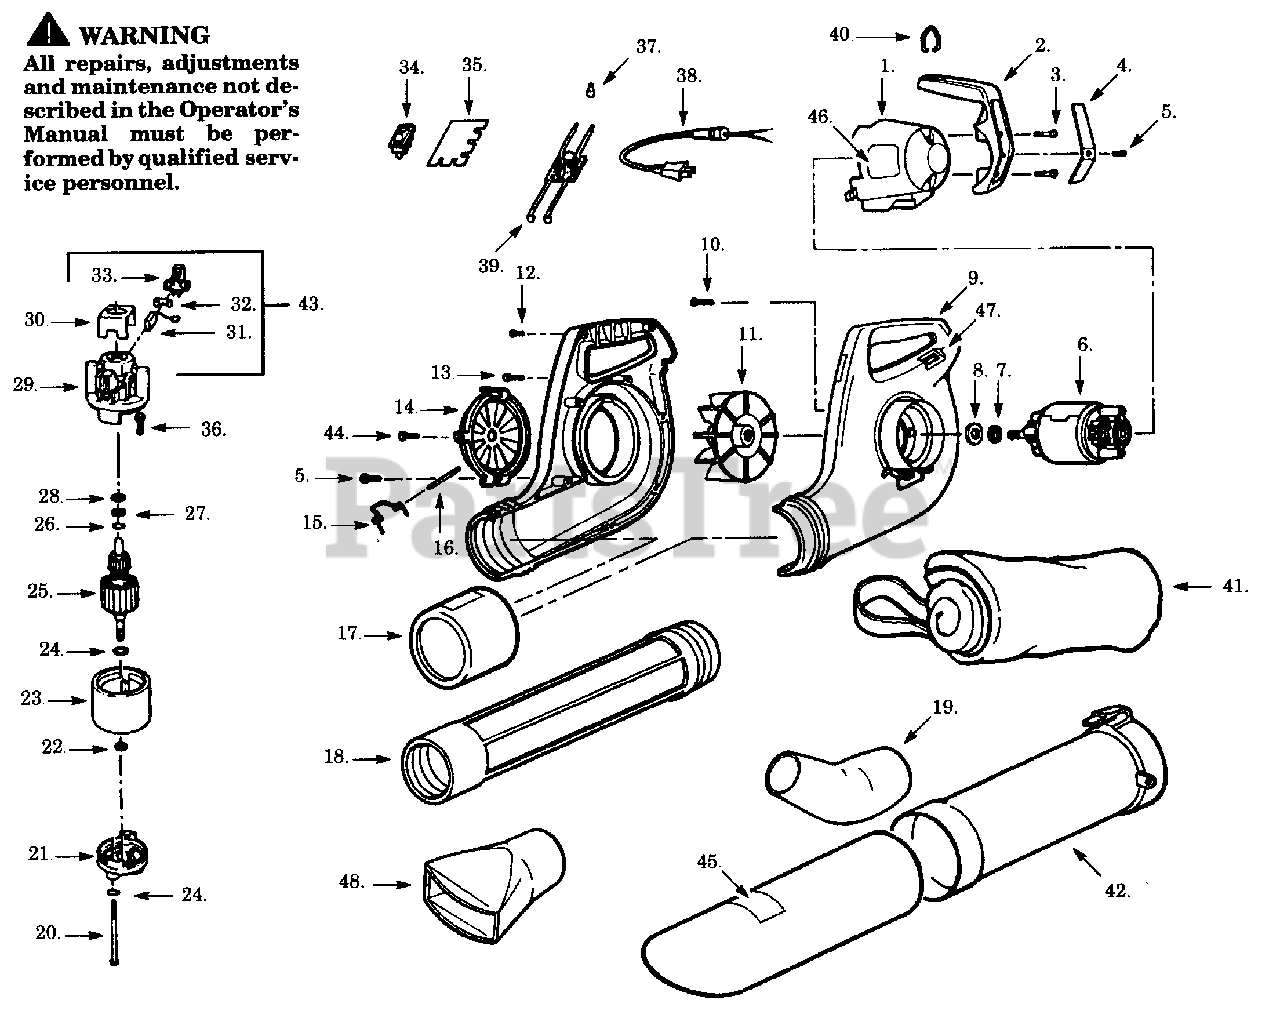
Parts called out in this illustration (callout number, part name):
1	Motor Cover
4	Plate Warning
7	Retaining Ring
9	L.H/R.H. Housing
11	Impeller Ass'y.
14	Inlet Cover
16	Hinge Pin
17	Ferrule Sleeve
18	Outlet Tube
19	Concentrated Nozzle
21	Endbell Ass'y. (Drive)
23	Field Ass'y.
24	Retaining Ring
25	Armature Ass'y.
26	Retaining Ring
29	Endbell Ass'y. (Brush)
30	Insulator
32	Brush Spring
33	Brush Holder
34	On-Off Switch Ass'y.
35	Mounting Board
37	Wire Nut
38	Power Cord/Harness Ass'y.
39	P.C. Board Ass'y.
41	Vacuum Bag
42	Vacuum Tube
43	Brush Kit
45	Warning Label-Tube (Not a serviceable part)
46	Motor Cover Label (Not a serviceable part)
47	Switch Position Label
48	Flare Nozzle
